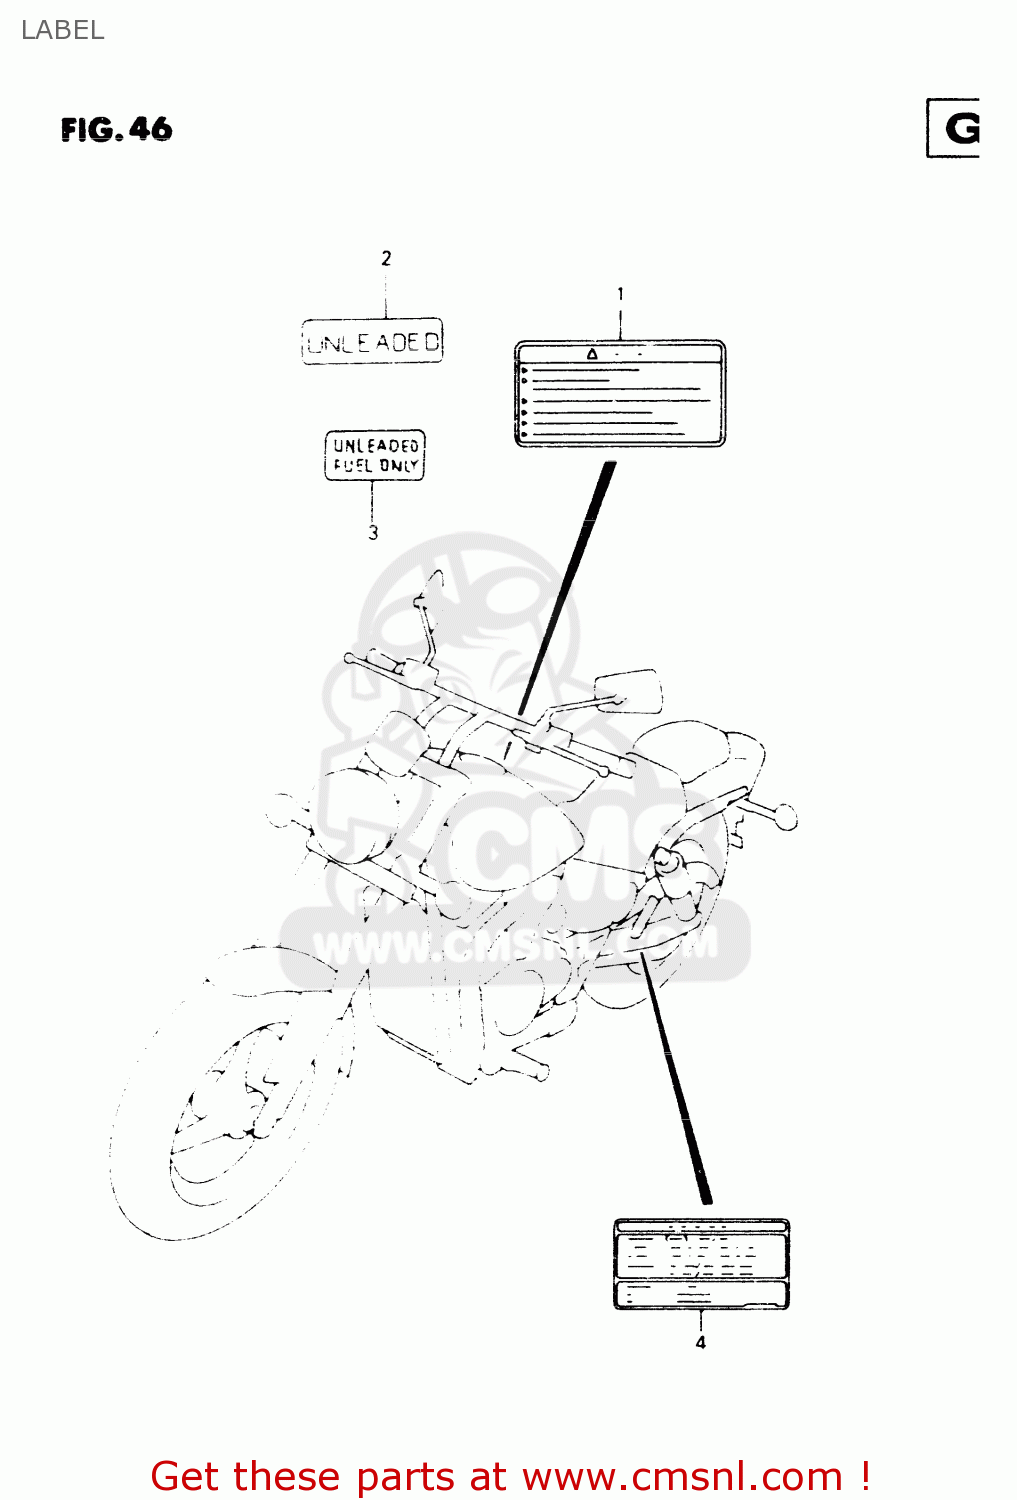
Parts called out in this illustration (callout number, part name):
1	LABEL,WARNING
2	LABEL,CAUTION
3	LABEL,FUEL CAUTION
4	LABEL,TIRE AIR PRESSURE
5	MANUAL, OWNERS
